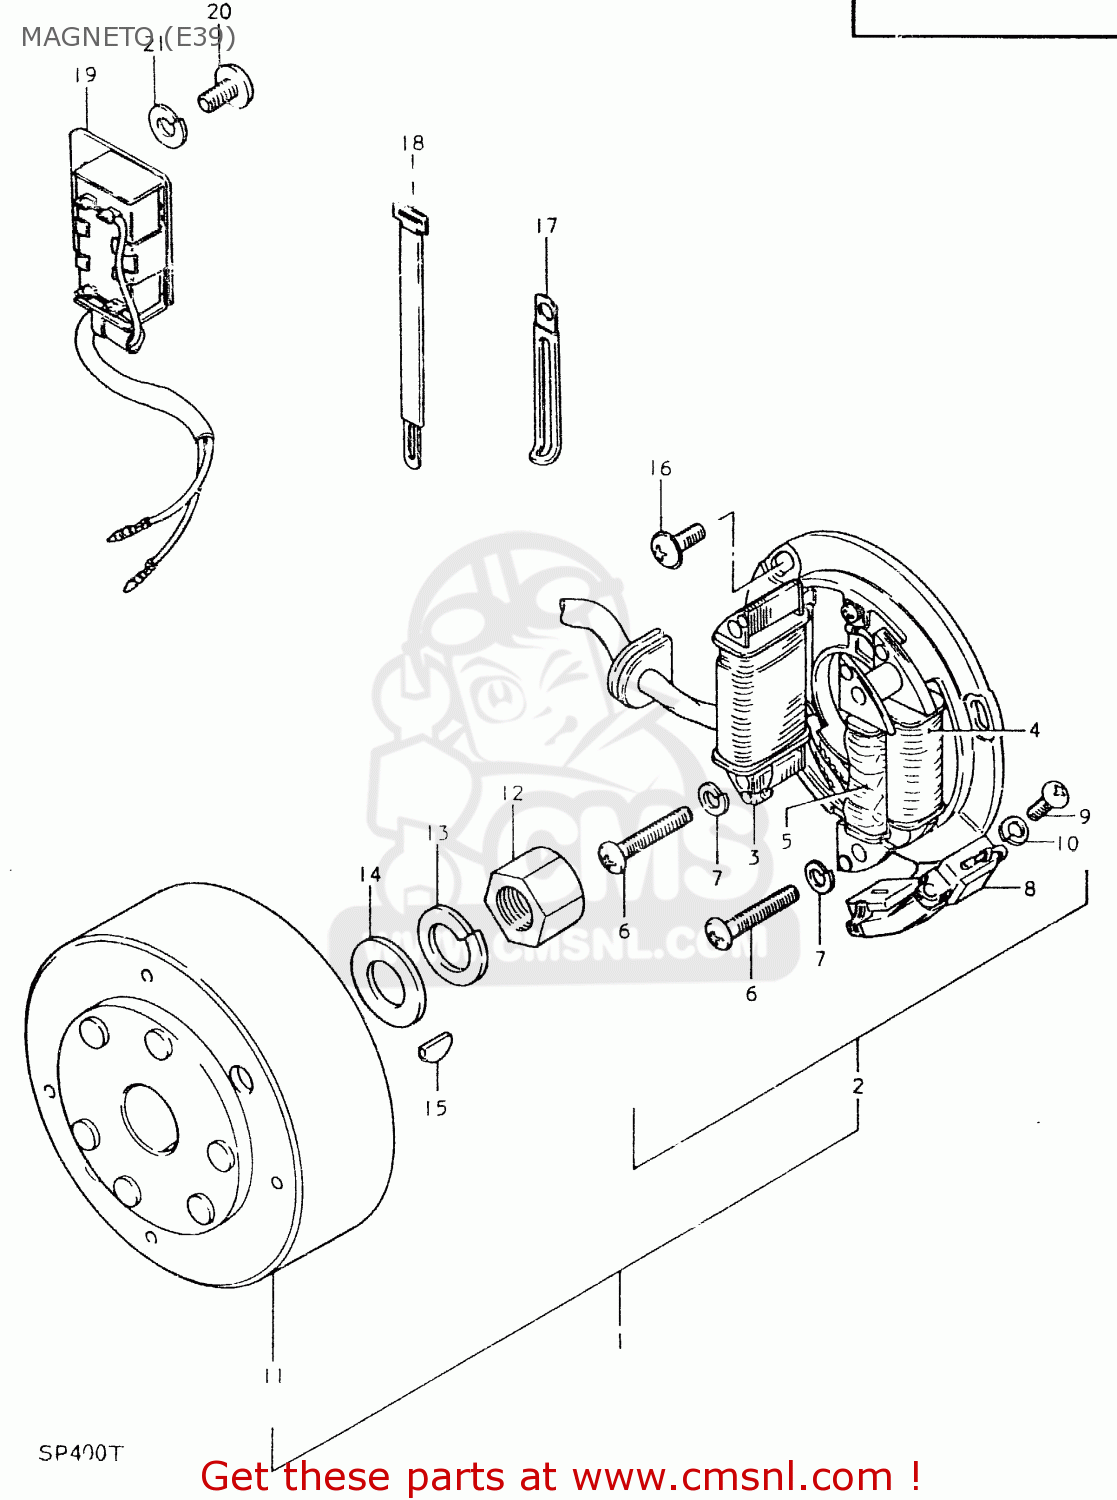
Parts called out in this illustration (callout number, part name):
1	MAGNETO ASSY
2	STATOR ASSY
3	COIL, LIGHTING
4	COIL,PRIMARY
5	COIL,PULSER
6	SCREW
7	LOCK WASHER
8	COIL,PULSER
9	SCREW
10	LOCK WASHER
11	ROTOR ASSEMBLY
12	NUT
13	LOCK WASHER
14	WASHER(14X27X3)
15	KEY 4MM
16	SCREW(5X14)
17	CLAMP
18	CLAMP
19	REGISTER ASSEMBLY
20	SCREW 6X12
21	LOCK WASHER
